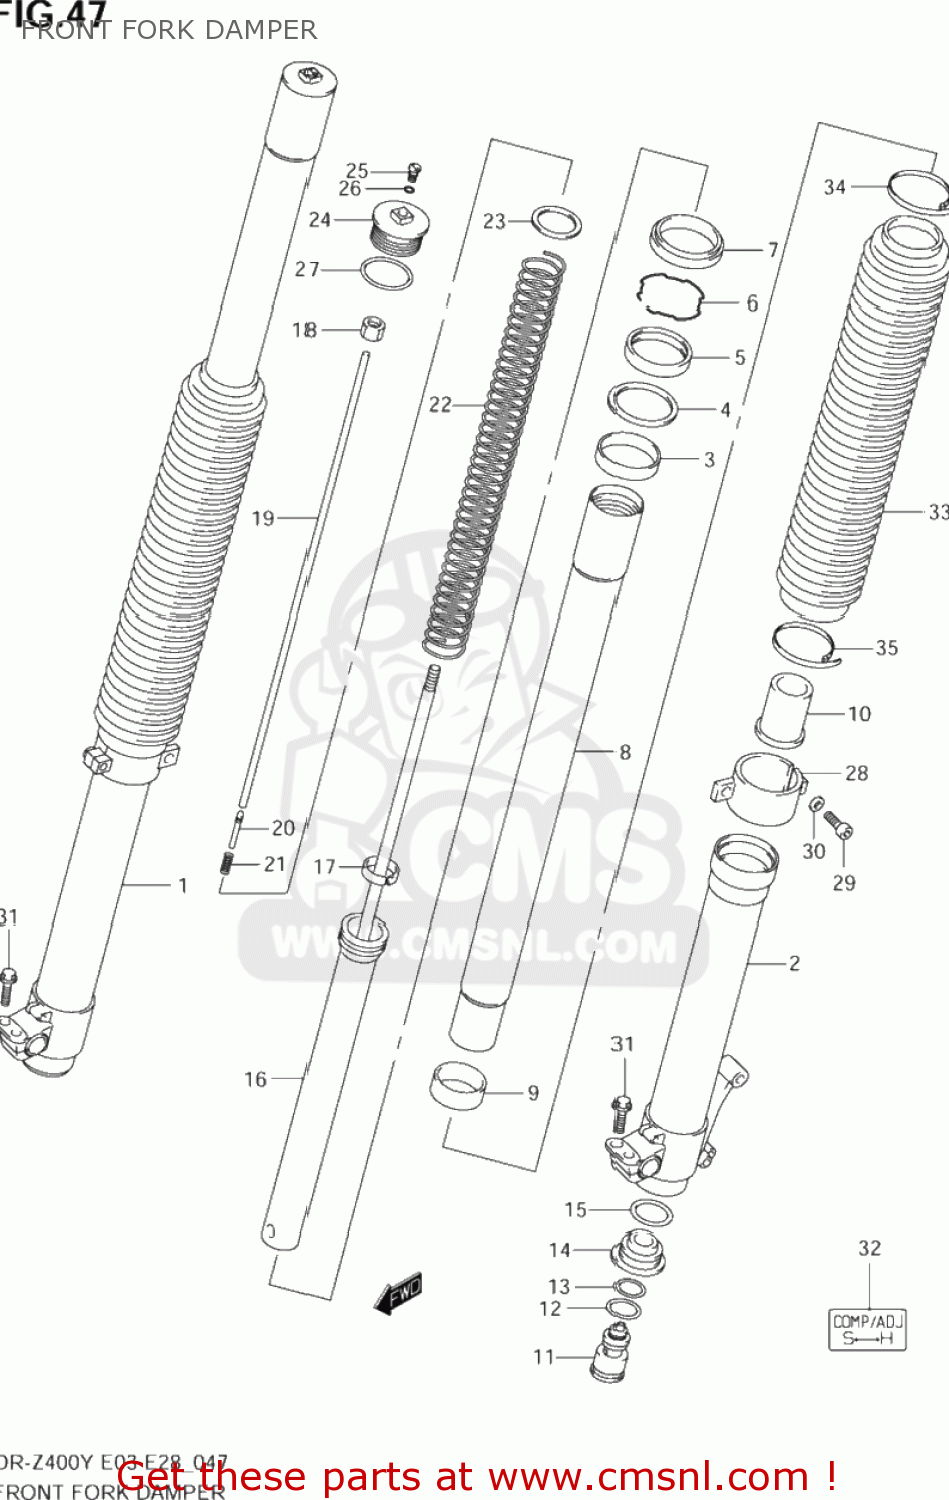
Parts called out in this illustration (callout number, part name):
1	TUBE,OUTER,R
2	TUBE,OUTER,L
3	BUSH,GUIDE
4	SPACER,SEAL
5	SEAL,OIL
6	RING,STOPPER
7	SEAL,DUST
8	TUBE,INNER
9	BUSH,SLIDE
10	PIECE,OIL LOCK
11	BOLT,CTR
12	O RING
13	O RING
14	PLATE,END
15	O RING
16	ROD,FR DAMPER
17	BUSH,SLIDE
18	NUT
19	ROD,PUSH
20	NEEDLE
21	SPRING,PUSH ROD
22	SPRING,FR(SOFT)
23	JOINT,SPRING
24	BOLT,FORK
25	BOLT,PLUG
26	O RING,PLUG
27	O RING
28	HOLDER,BOOT
29	BOLT
30	WASHER(5.5X10X1)
31	BOLT,HANDLE HOLDER(8X35)
32	LABEL
33	BOOT
34	BAND,BOOT UPR
35	BAND,BOOT LWR
